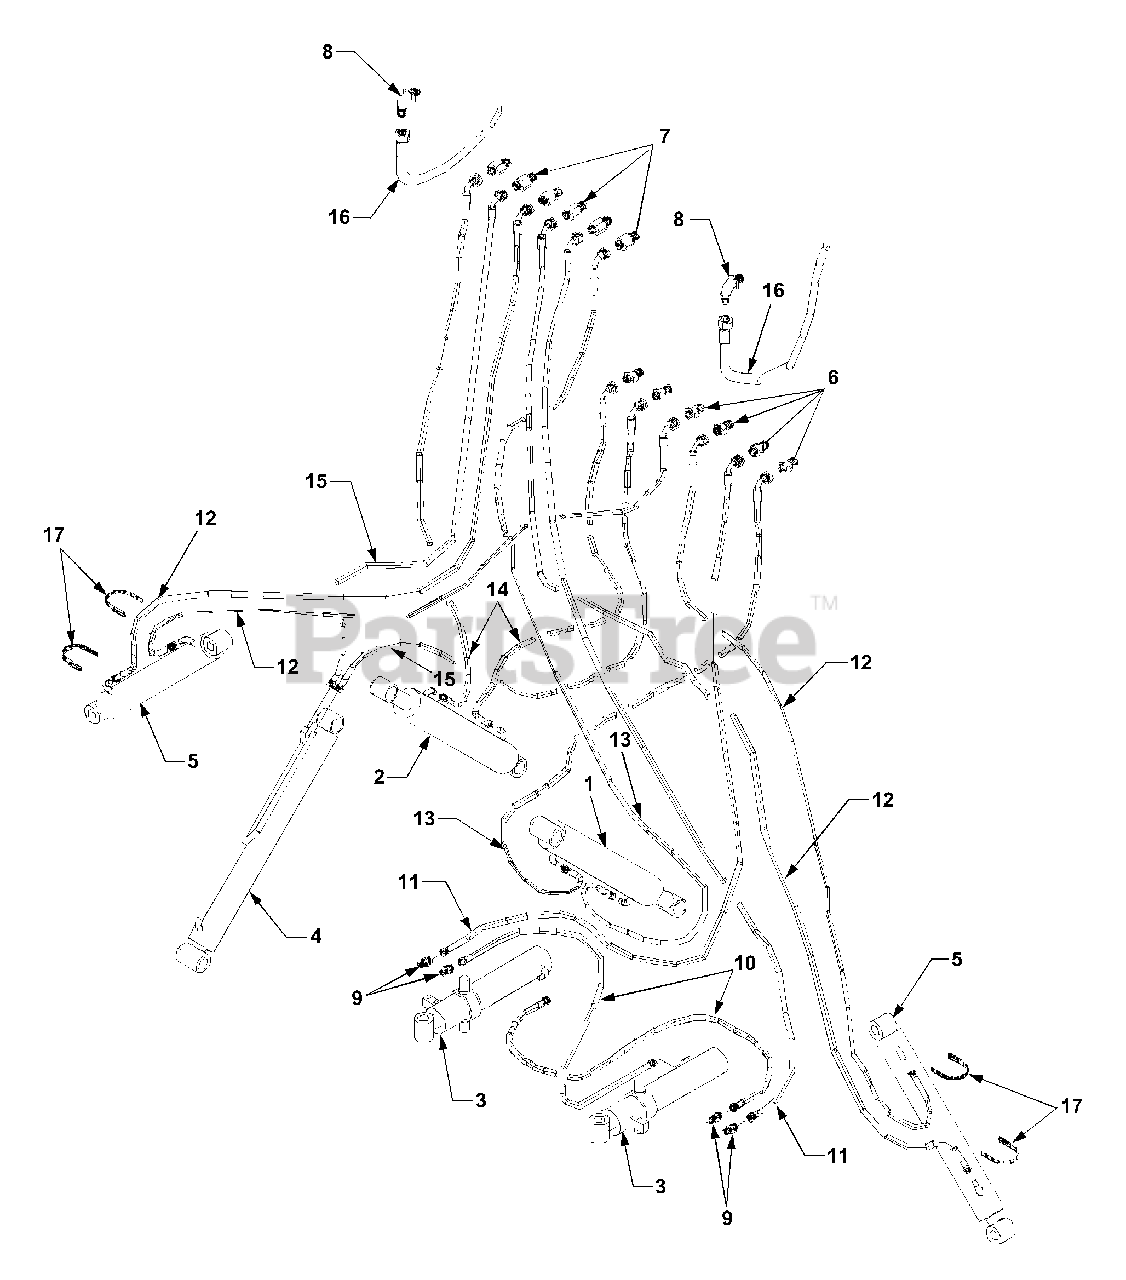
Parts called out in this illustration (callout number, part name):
1	Boom Cylinder Ass'y.
2	Dipperstick Cylinder Ass'y.
3	Swing Cylinder Ass'y.
4	Bucket Cylinder Ass'y.
5	Stabilizer Cylinder Ass'y. LH
6	Adapter w/O-ring
7	Adapter w/O-ring
8	Adapter Elbow
9	Nipple w/O-ring
10	Hose,(Swing to Swing)
11	Hose (Swing to Valve)
12	Hose (Stabilizer)
14	Hose (Dipperstick)
15	Hose (Bucket)
16	Hose, (Valve in & out)
